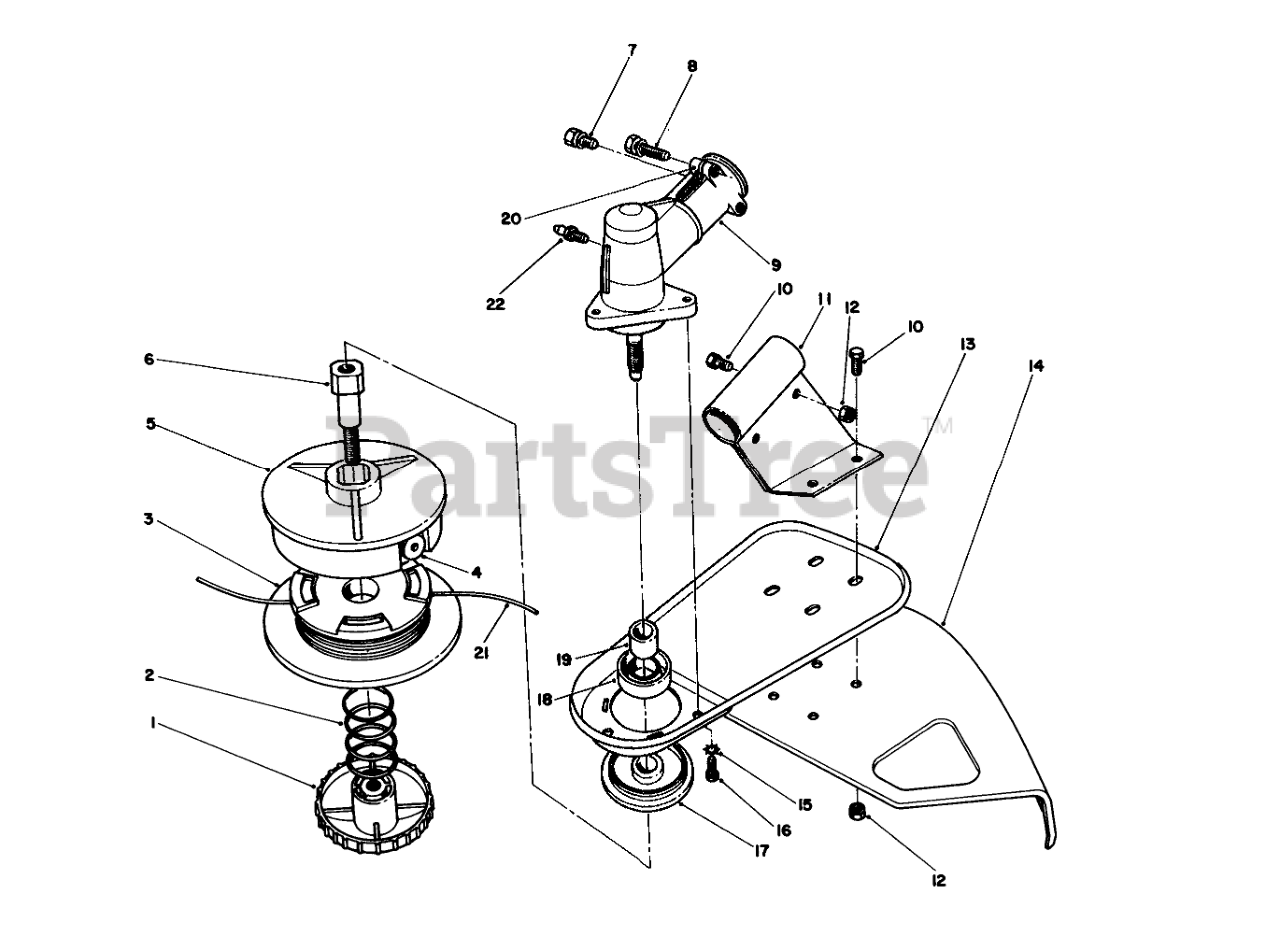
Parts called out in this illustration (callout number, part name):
1	Knob-L.H.
2	Spring
3	Spool-Inner
4	Eyelet
5	Housing-Spool
6	SHAFT ADAPTER
7	HHMS SCREW
8	HHMS SCREW
9	Gear Box Assembly (Incl.Ref. #7, 8, 17-20)
10	SCREW-SHH
11	Bracket-Shield
12	NUT-LOCK, NI
13	SHIELD SUPPORT R
14	GRASS SHIELD-STEEL
15	WASHER-LOCK, EXT
16	SCREW
17	DUST CAP F/W
18	OIL SEAL
19	SPLINED SLEEVE
20	WASHER
21	REPL LINE PKG
